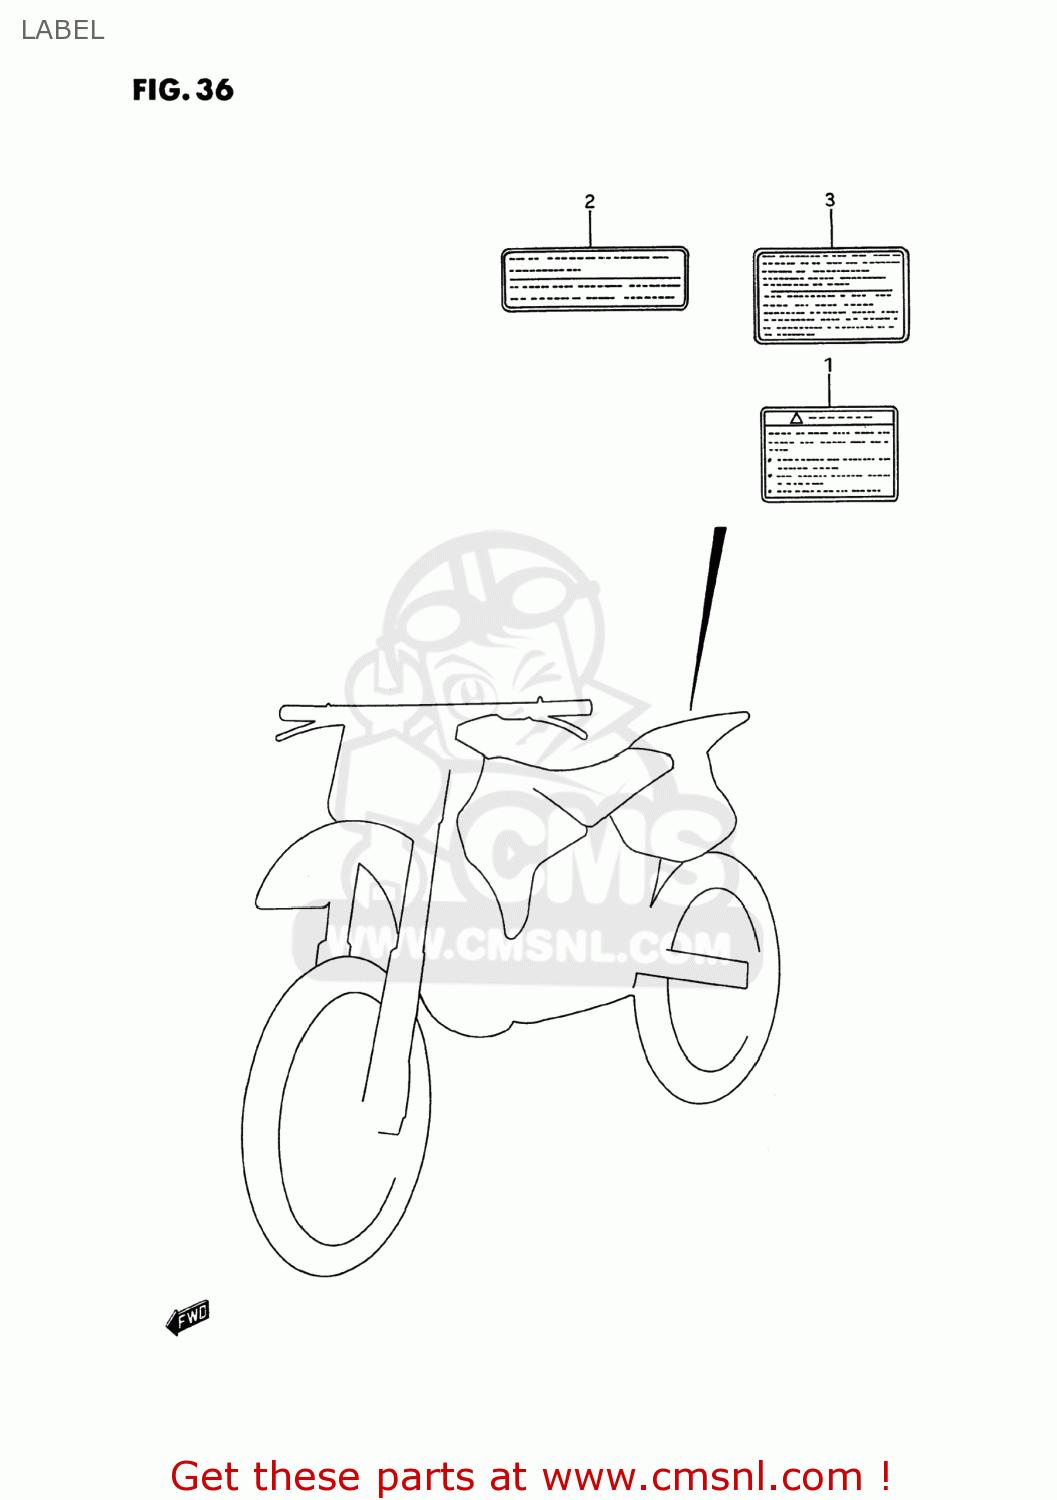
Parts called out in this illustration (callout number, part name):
1	LABEL
2	LABEL,WARNING NO.2
3	LABEL,WARNING
4	LABEL,WARNING
